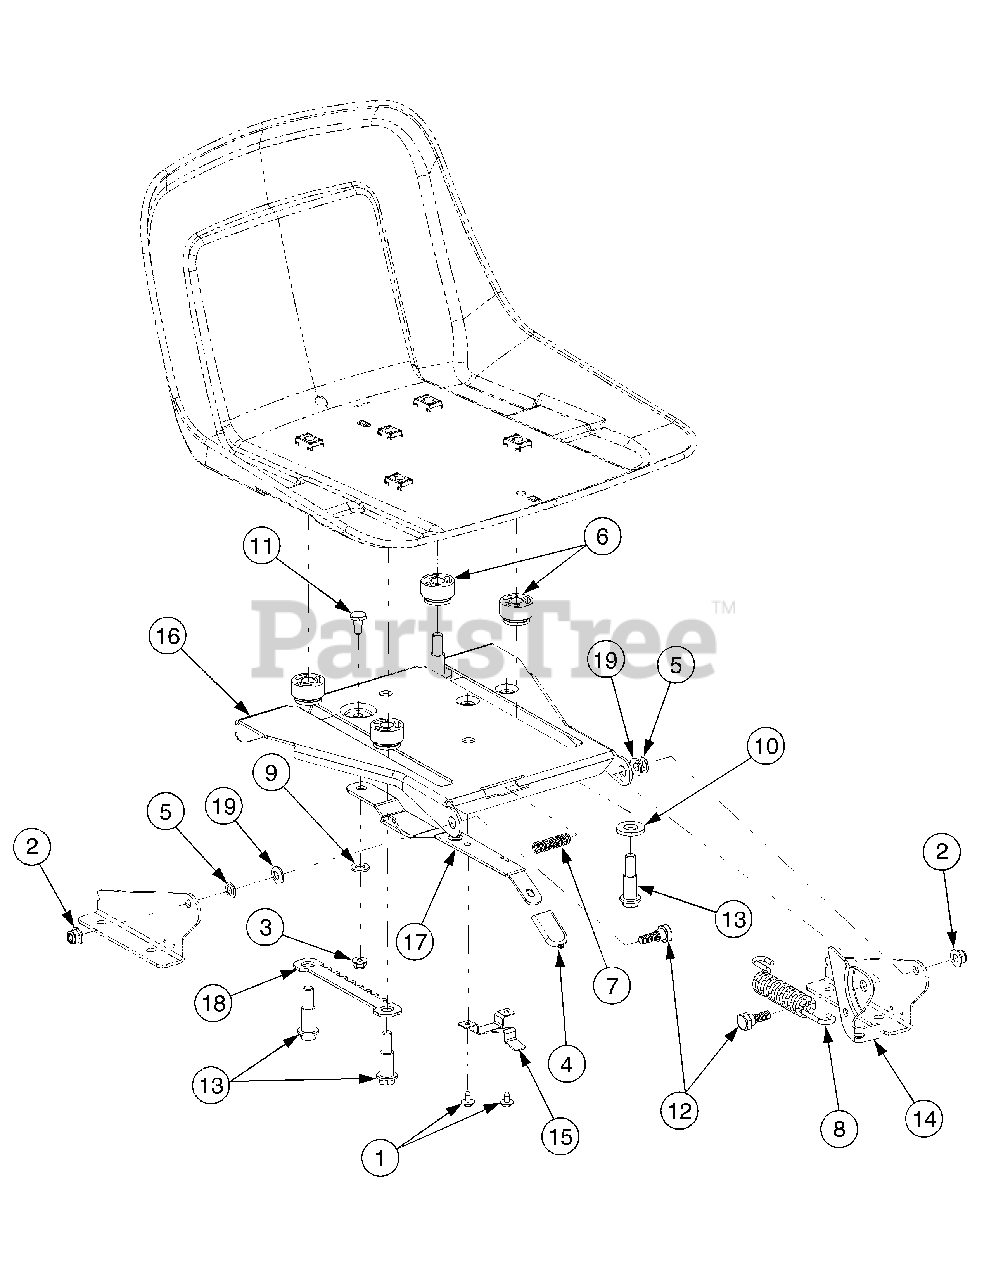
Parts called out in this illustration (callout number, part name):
1	Screw, Hx. Wash. Hd. Tapp #10-16 x .375
2	Nut, Hx Insert Flange Lck, 5/16-18 GrF
3	Nut, Hx Insert Flnge Lck, 1/4-20 GrF
4	Grip, Seat Adjustment
5	Nut, Speed, .3125
6	Spacer, Seat Adjustment
7	Spring, Compression, .41 x 1.5
8	Spring, Extension, .84 Dia. x 4.6
9	Washer, Flat, .344 x .62 x .033
10	Washer, Flat, .531 x 1.062 x .134 HT
11	Screw, Shoulder, .34 x .285:1/4-20
12	Screw, Shoulder, .437 x .268:5/16-18
13	Screw, Shoulder, .5 x .925:3/8-16 ...
14	Bracket, Seat Lift
15	Stop, Seat Adjustment
18	Index Bracket, Seat Adjustment
19	Washer, Belleville, .34 x .872 x .06
